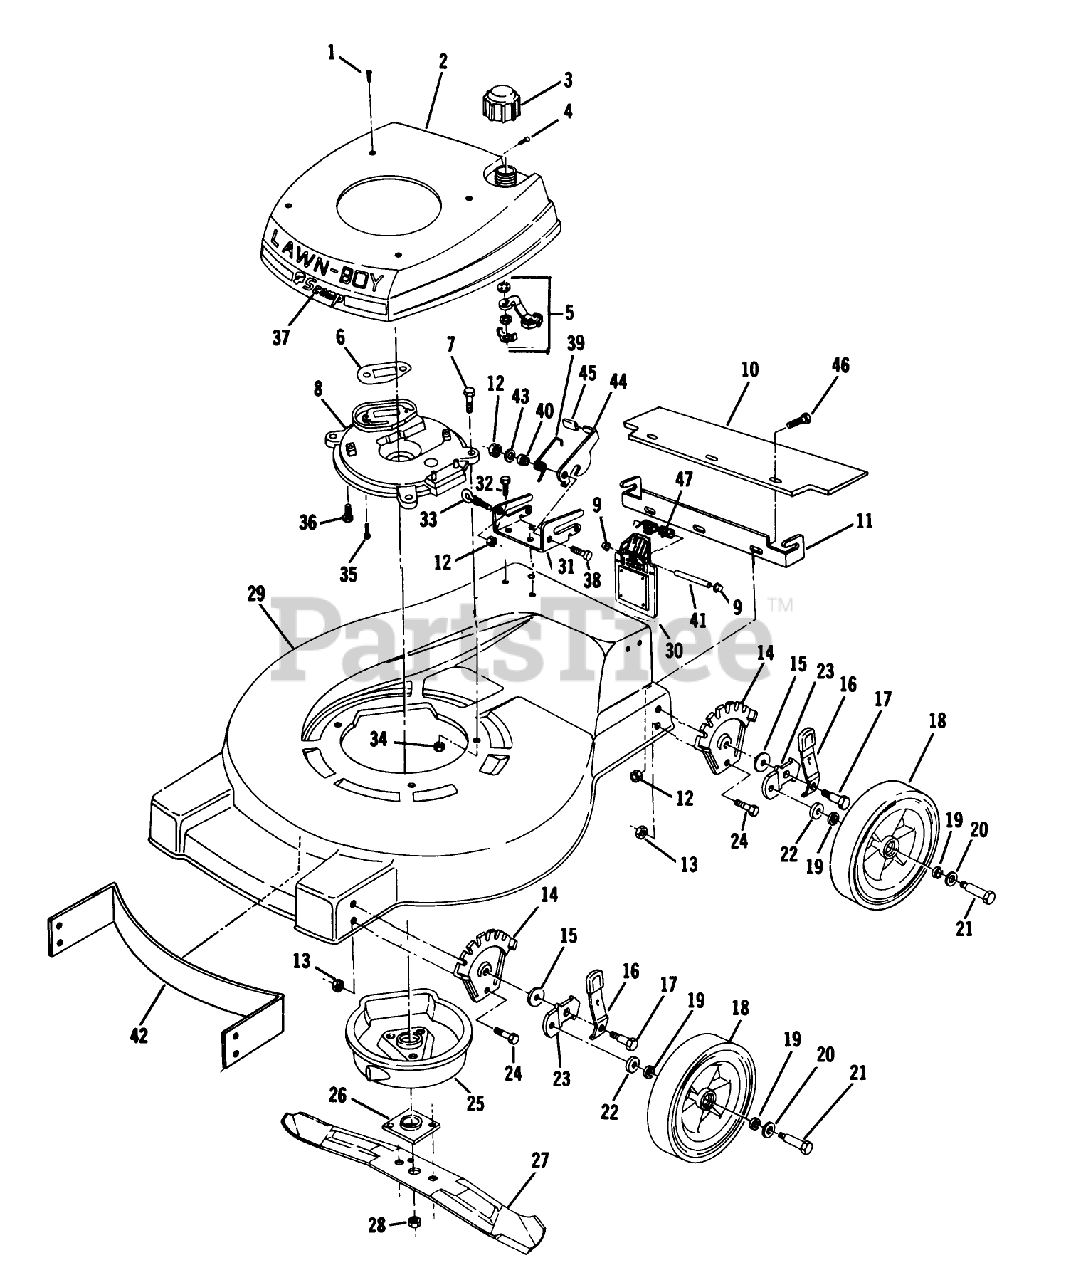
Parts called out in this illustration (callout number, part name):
1	SCREW LAWRENCE
3	FUEL CAP & INSERT
4	SCREW S
8	PLATE,MUFFLER F
12	LOCKNUT E
13	LOCKNUT
16	KNOB & SPRING
21	BOLT WHEEL
22	WASHER WROUGHT
26	PLATE AND COLLAR ASM
28	NUT-BLADE
33	BOLT-EYE
34	NUT-LOCK F
35	SCREW V
41	ROD ROCK/HDWE
47	SPRING ASOC
